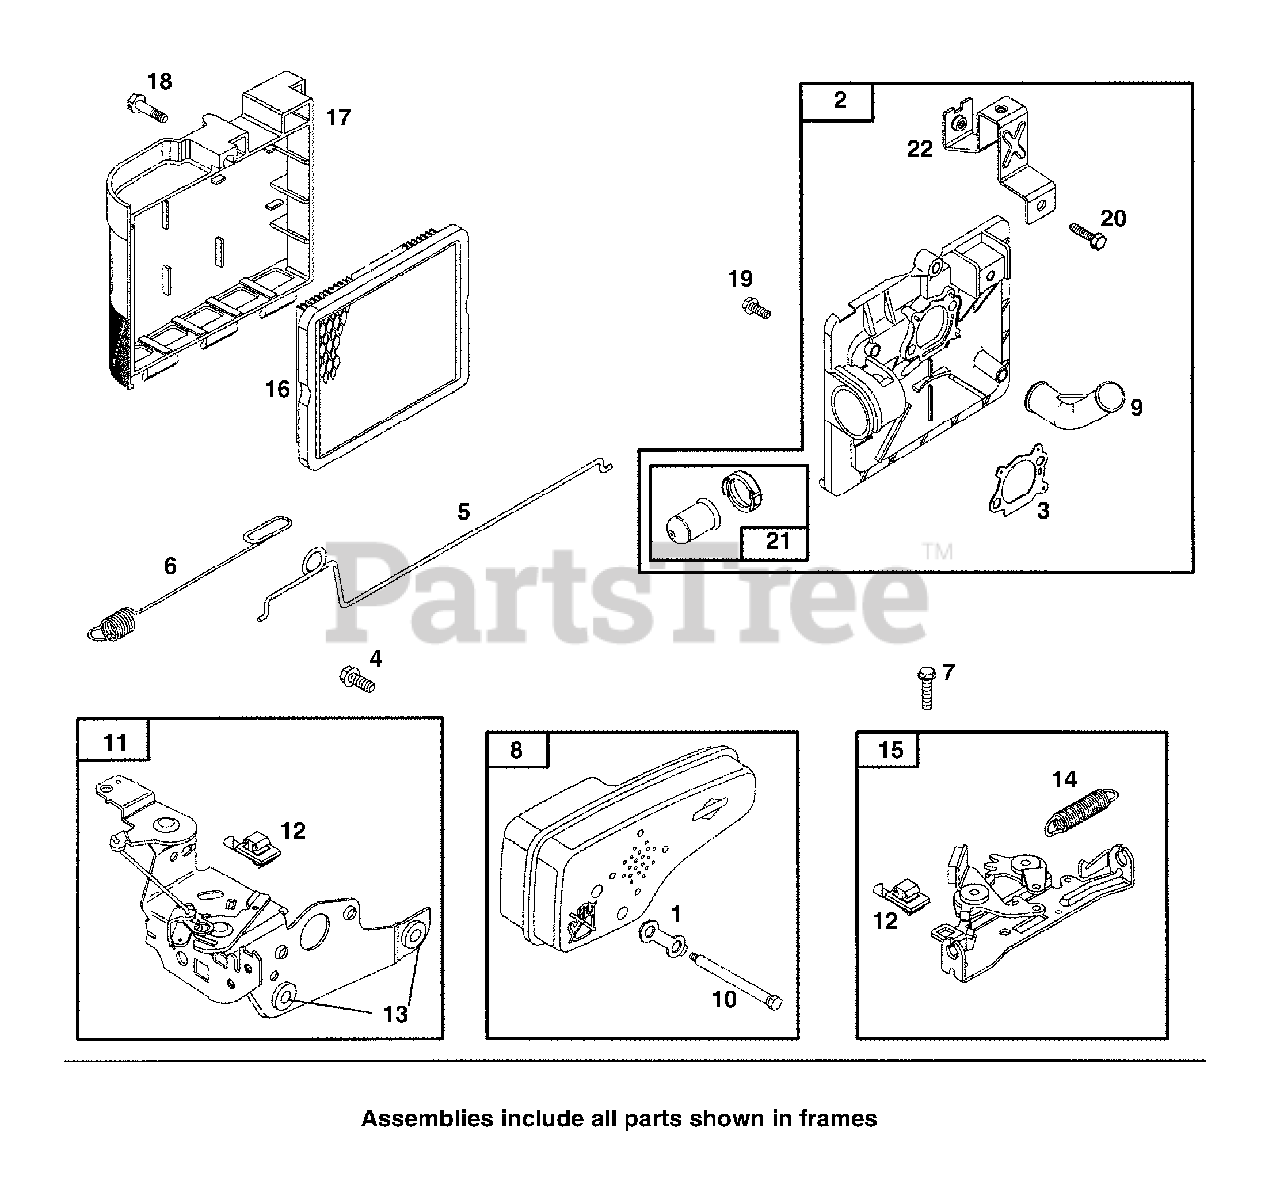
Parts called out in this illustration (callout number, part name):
1	Muffler Screw Lock
2	Air Cleaner Base
3	A/C Primer Gasket
4	Hex Screw
5	Mechanical Governor Link
6	Governor Spring
7	Slotted Hex Screw
8	Exhaust Muffler
9	Grommet
10	Shoulder Screw
11	Control Bracket
12	Stop Switch
13	Spacer
14	Brake Spring
15	Brake
16	A/C Cartridge Filter
17	Air Cleaner Cover
18	Slotted Hex Screw
19	Hex Screw
20	Hex Screw
21	Carburetor Primer
22	Air Cleaner Support
